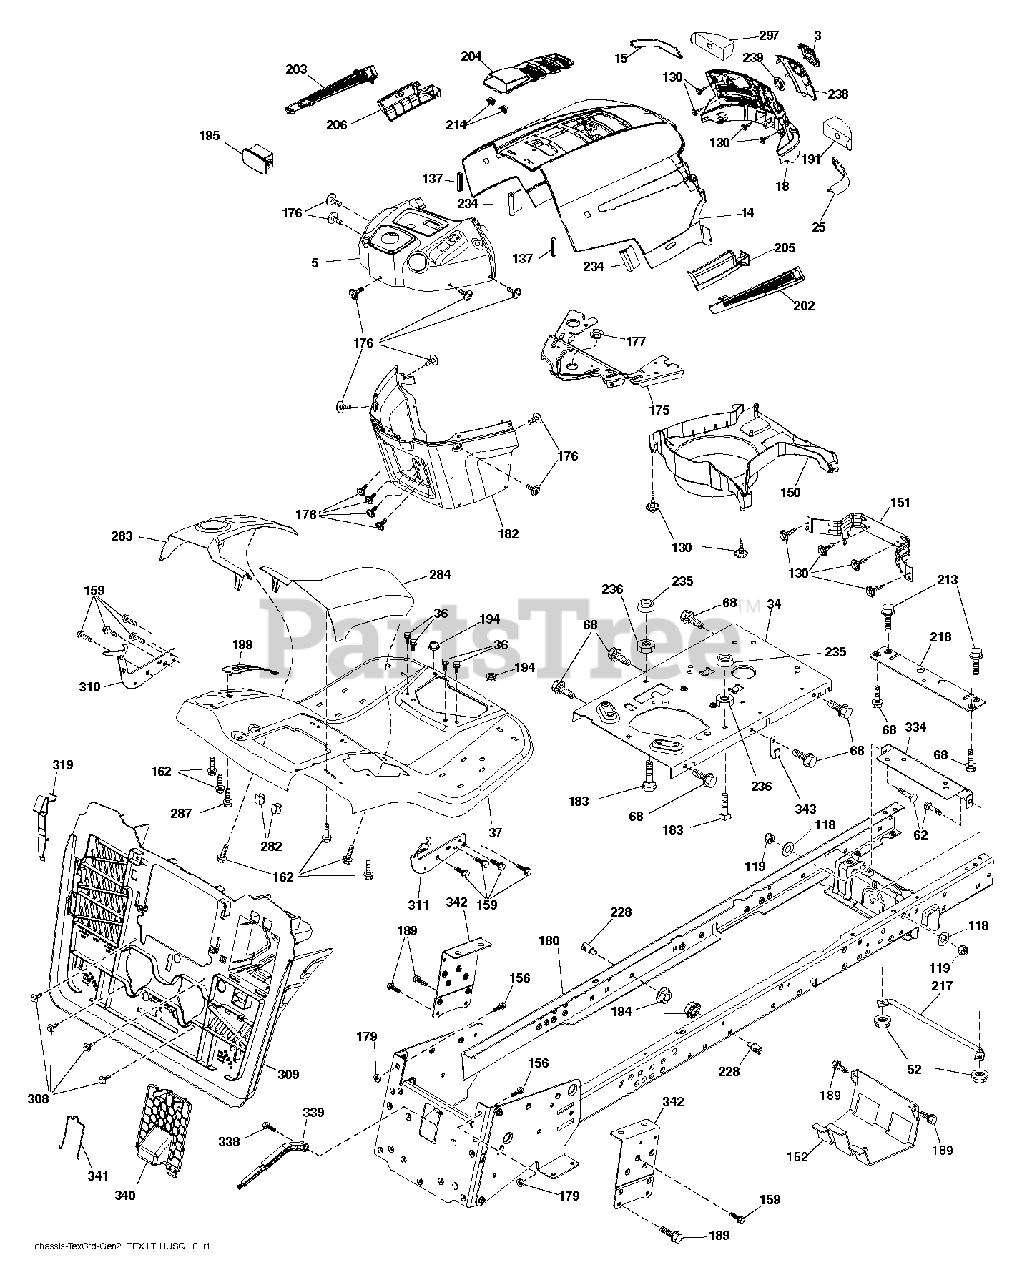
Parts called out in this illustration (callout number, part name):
3	LOGO.HUSQ.GT.LT.CROWN.H
14	HOOD.HUSQVARNA.LT.ORANGE
15	LENS.HUSQVARNA LT.RH
18	GRILLE.SVC.HUSQVARNA.GREY
25	LENS.HUSQVARNA LT.RH
34	PLATE.ENGINE.10GA.CRD.GENII
36	SCREW 5/16"
37	FENDER.TEX.SRD.CRD.FRN.GUARDS
52	LOCKNUT
62	BOLT D
68	SCREW LT
118	WASHER
130	SCREW.#10 X 0.750.BOS
137	BUMPER DASH
151	BRACKET PIVOT
152	SHIELD.BROWNING.W/TEX
159	SCREW, 3/8-16X3/4
162	SCREW.HI-LO.CONSOLE
175	CROSSMEMBER
176	SCREW.#10-24X5/8.RN.QU
177	BUSHING STEERING
180	CHASSIS WLDT TEX CRD
182	DASH.LOWER.PREDATOR LT
183	BOLT.5/16-18X1-1/4 FULL THD
189	SCREW
191	INSERT.REFLECTIVE.RH.
194	NUT LOCK HEX FLANGE 5/16-18
195	PLUG.HOLE.DASH.LOWER.12V.BLK
199	PLATE DECK LIFT
202	VENT.SIDE.HUSQVARNA.LT.RT
203	VENT.SIDE.HUSQVARNA.LT.LFT
204	SUBASM.TOP.VENT.HUSQ.LT
205	SKIRT.SIDE.HUSQVARNA.LT.RT
206	SKIRT.SIDE.HUSQVARNA.LT.LEFT
213	BOLT
214	CLIP.RETAINER.TINNER.
217	ROD.PIVOT.HOOD
218	X-PIECE.HOOD.STOP.NON/
228	STUD.FASTNER.W/ANTI-ROTATE
234	BUMPER.HOOD.TEX.HUSQVARNA
235	SPACER FENDER
236	NUT.CENTERLOCK.5/16-
238	TRIM.HUSQ LT.668
282	CLIP.RETAINER.CONSOLE.LT.HUSQ
283	CONSL.DECKLIFT.LH.SRD.TEX.CRD
284	CONSL.SHFT.PEDAL.RH.SRD.TEXCRD
287	SCREW 1/4X20
297	INSERT REFLECTIVE
308	BOLT, 5/16-18 X 1 3/4
309	BACKPLATE.TEX.CRD
310	LH.ADJUST.HANGER.BRACKET.ASM
311	RH.ADJUST.HANGER.BRACKET.ASM
319	BRACKET.ACTUATOR.BAGGER.SRD
334	BRACKET.ENGINE
338	BOLT BOLT SHOULDER
339	LEVER LEVER BAGGER
340	DOOR.PNT.BATTERY.TRY.TEX.CRD.
341	LATCH
342	SUPPORT SUPPORT FENDER
343	CLIP CLIP
